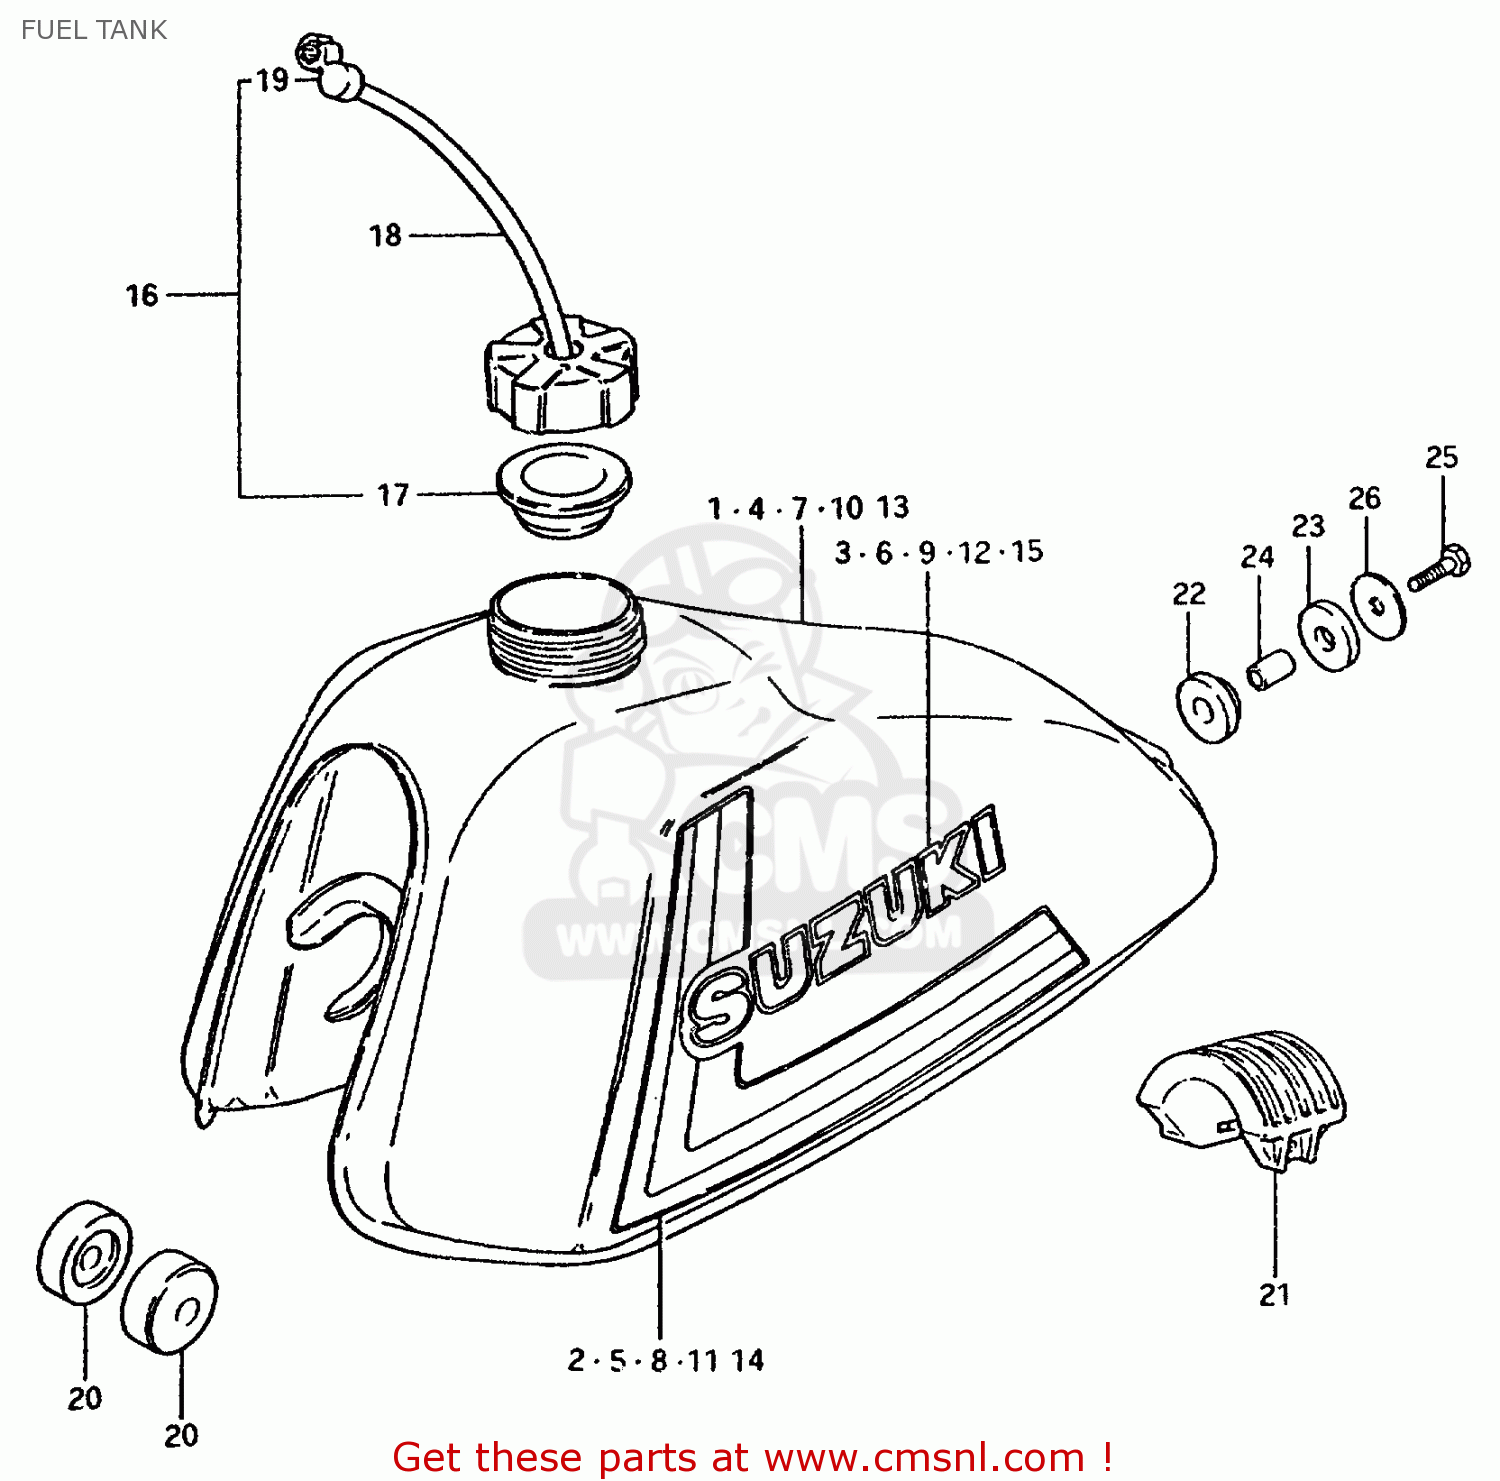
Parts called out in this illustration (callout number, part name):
1	TANK, FUEL (RED)
2	TAPE SET
3	EMBLEM
4	TANK, FUEL (BLUE)
5	TAPE SET
6	EMBLEM
7	TANK, FUEL (WHITE)
8	TAPE SET
9	EMBLEM(BLACK)
10	TANK, FUEL (BLUE)
11	TAPE SET
12	EMBLEM
13	TANK, FUEL (YELLOW)
14	TAPE SET
15	EMBLEM(BLACK)
16	CAP SET,FUEL TANK
17	GASKET,FUEL TANK CAP (NAS)
18	HOSE
19	CLAMP,FUEL TANK BREATHER HOSE
20	CUSHION
21	CUSHION,FUEL TANK
22	CUSHION
23	CUSHION
24	SPACER(8.5X12X19)
25	BOLT (8X30)
26	WASHER (8.5X29X1.6)
